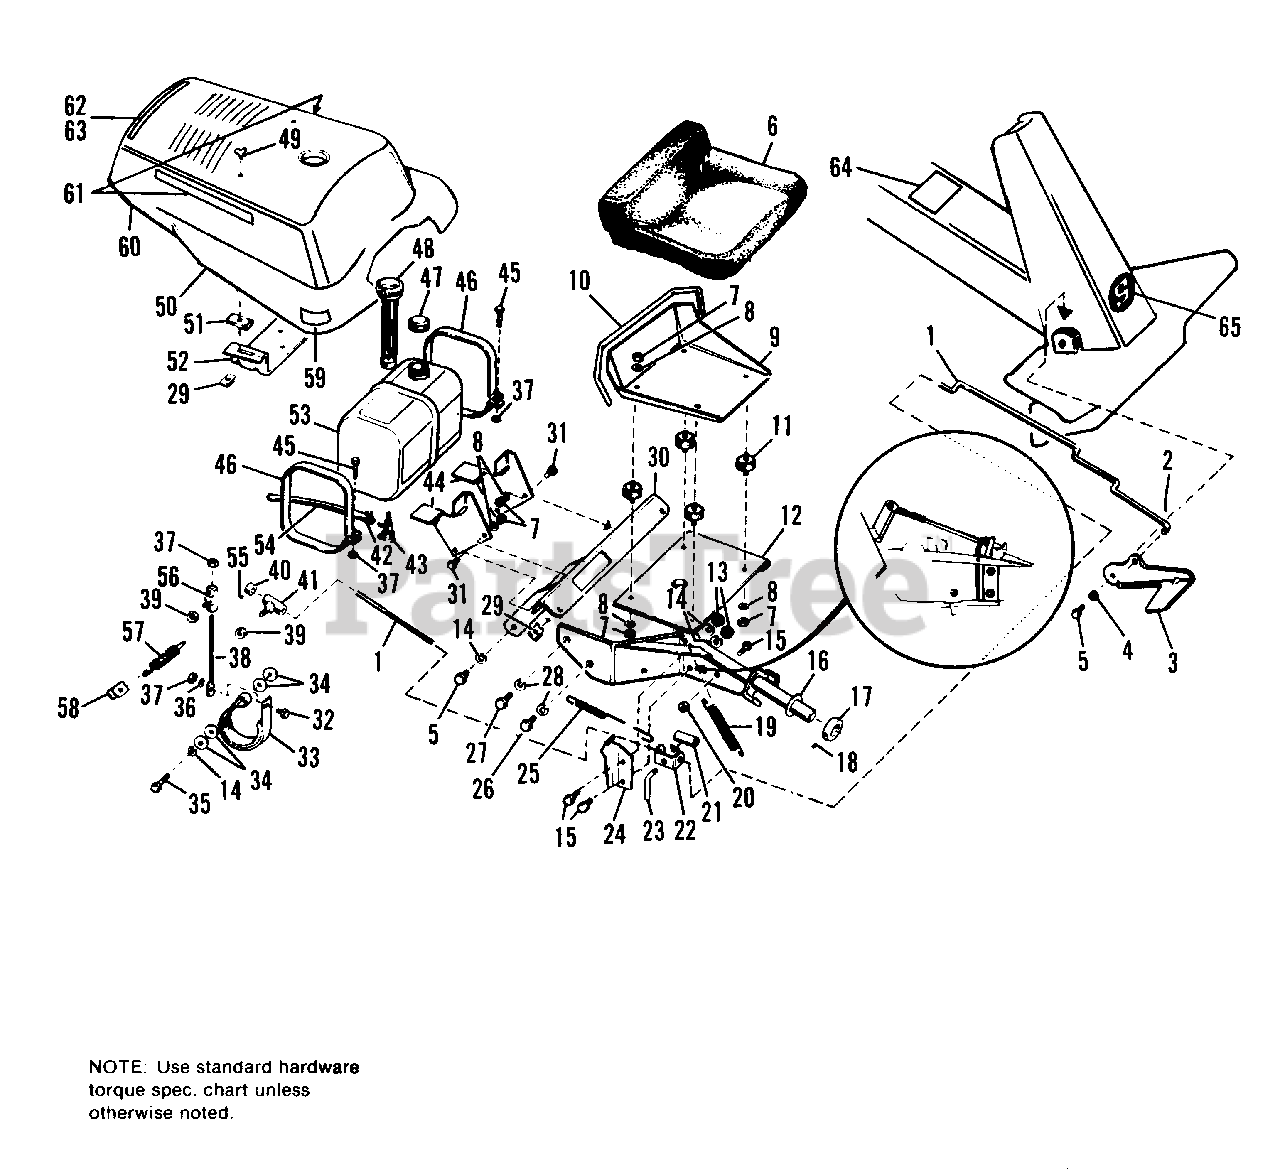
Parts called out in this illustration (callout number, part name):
1	ROD, Foot Pedal
2	PIN, Cotter, 3/32 x 5/8
3	PEDAL, Foot
4	LOCKNUT, Hex, 3/8-16
5	CAPSCREW, Hex Hd., 3/8-16 x 7/8
6	PAD, Seat
7	NUT, Hex, Full, 5/16-18
8	LOCKWASHER, 5/16
9	PANEL, Seat
10	APE, 2 ft.
11	CONNECTOR, Cushion
12	SUPPORT ASSY.
13	NUT, Hex, Full, 3/8-16
14	LOCKWASHER, 3/8
15	CAPSCREW, Hex Hd., 3/8-16 x 1-1/4
17	COLLAR, Set
18	SETSCREW, 5/16-18 x 3/8
19	SPRING
20	LOCKNUT, Jam, 3/8-16
22	BRACKET ASSY.
23	LOCK, Parking Brake
24	BRACE, Brake
26	CAPSCREW, Hex Hd., 7/16-14 x 1
27	CAPSCREW, Hex Hd., 7/16-14 x 1-1/4
28	LOCKWASHER, 7/16
29	NUT, Speed, 5/16-18
30	SUPPORT ASSY., Hood
31	CAPSCREW, Hex Hd., 5/16-18 x 3/4
32	CAPSCREW, Hex Hd., 1/4-20 x 1/2
33	BAND ASSY., Brake
34	WASHER, Plain, 5/16
35	CAPSCREW, Hex Hd., 3/8-16 x 1-1/2
36	LOCKWASHER, 1/4
37	NUT, Hex, Full, 1/4-20
38	ROD, Brake
39	LOCKNUT, Hex, 5/16-18
40	COLLAR, Set
41	GUIDE ASSY., Rod
42	CLAMP, Hose
43	VALVE, Shut Off
44	SUPPORT, Fuel Tank
45	CAPSCREW, Hex Hd., 1/4-20 x 1-3/4
46	STRAP, Tank
47	CAP, Fuel Tank
48	CAP, Fuel Tank
49	SCREW, Thumb
51	GASKET, Felt
52	BRACKET, Hood
53	TANK, Fuel
54	HOSE, Fuel
55	SETSCREW, 1/4-20 x 3/8
56	GUIDE ASSY., Rod
57	SPRING
58	CLIP, Spring
62	DECAL, W.B. Special
63	DECAL, W.B. Super
